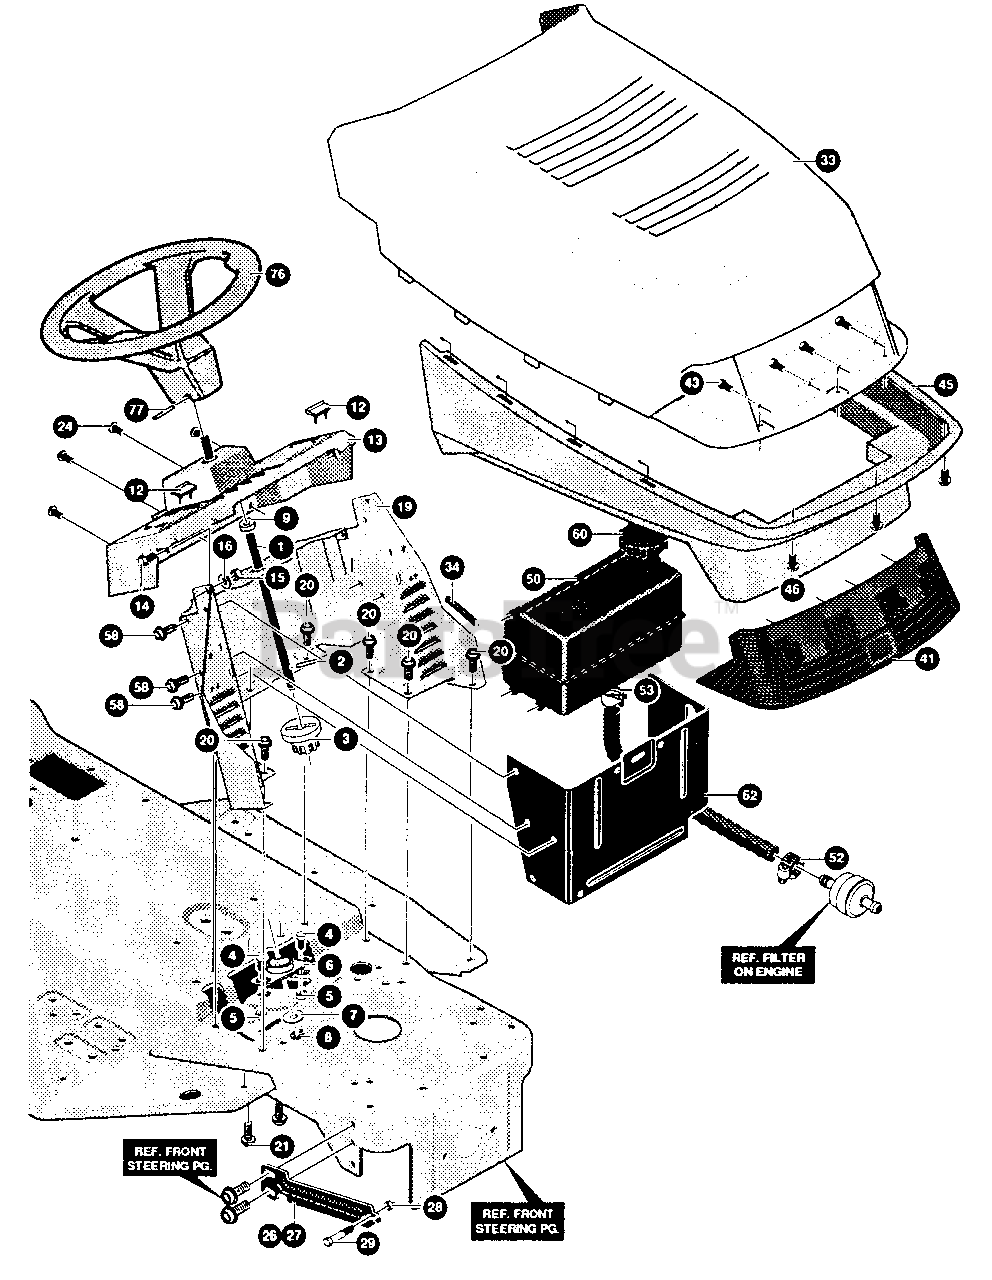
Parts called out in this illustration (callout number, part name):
1	SHAFT, STEERING EURO LT SHORT
2	PIN DOWEL STR ERO LT
3	PINION, STEERING
4	SCREW, 5/16-24X.75 (TQ 30-35 FT#)
5	NUT, 5/16-24 HEXWDFLLK
6	BEARING, SFAL .500IDX.ODX.75
7	WASHER, FLAT .504X.75X.059
8	RING, RET E.39X.04 TRU5 133-50
9	BUSHING STR SHFT UPPER
12	BUMPER, HOOD/DASH EURO TOP
13	DASH,TALL
14	SCREW, 1/4-20X .75 HHC
15	NUT, 1/4-20 REGHEXCTRLK
16	WASHER. FLAT .281X .63X.065
19	DASH, LOWER
20	SCREW, 5/16-18X .50 WAHHTAP
21	SCREW, 5/16-18X .37 WAHHTAP
23	SCREW, 1/4-20X .50 WAHHTAP
24	SCREW, 1/4-20X.50PHPNTAP
26	BRACKET, HOOD RH
27	BRACKET, HOOD LH
28	NUT, 5/16-18 REGHEXCTRLK
29	BOLT, .500X.375 HHSH 5/16-18
33	HOOD, UPPER
34	EDGING, WIDE BLK
41	LENS, SMOKED GREY
43	SCREW. #10 X 50 HHTAPPST
46	SCREW, 1/4-14X.75PHPNHDTAP
50	ASSY GAS TANK 1.5 GAL
52	CLAMP, FUEL LINE
53	CLAMP,HOSE SCREW TYPE
58	SCREW, .25X.75X.51 HHWAPLASTITE
60	CAP FUEL 2.5" THROAT
62	HEAT SHIELD ERO 1.5 & 3 GAL
76	STEERING WHEEL
77	PIN SPRING.250DIAX2.00LG HVPL
